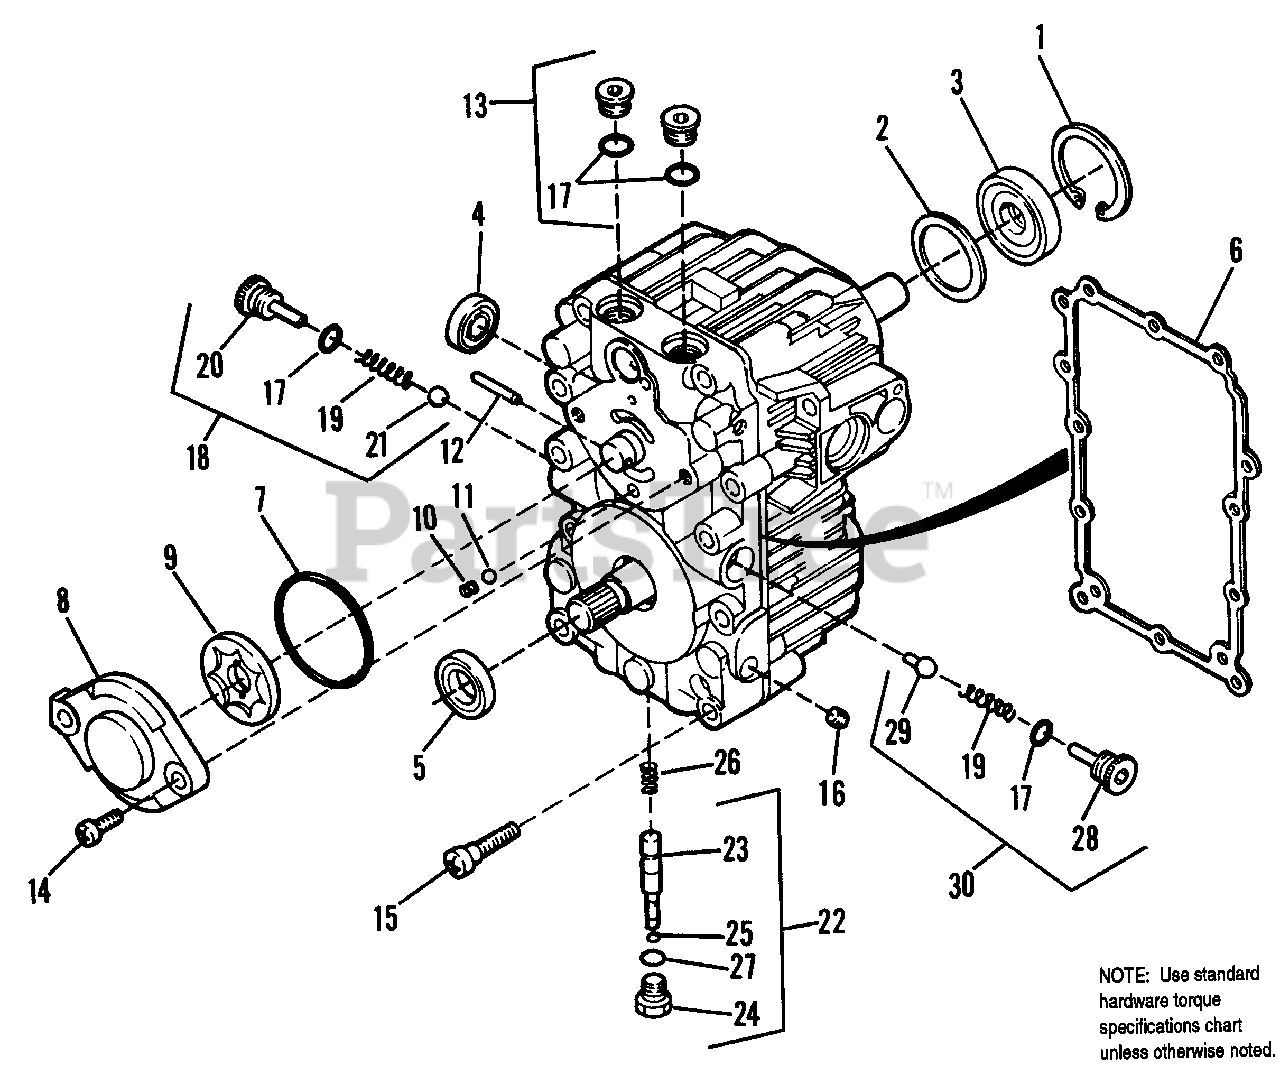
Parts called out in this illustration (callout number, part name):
1	RETAINING RING
2	SPACER
3	SEAL
4	SEAL
5	LIP SEAL
6	GASKET, Center Section
7	O-RING, Rubber
8	CHARGE PUMP HOUSING
9	GEROTOR ASSEMBLY
13	BOSS PLUG, O-Ring
14	SCREW, M8 x 20
15	SCREW, M8 x 35
17	O-RING, Rubber
18	CHECK VALVE KIT (Incl. Ref. Nos.17, 19, 20, 21)
19	SPRING
20	CHECK VALVE PLUG
22	BY-PASS VALVE KIT (Incl. Ref. Nos. 23-27)
23	BY-PASS SPOOL
24	BY-PASS PLUG
25	O-RING
27	O-RING, Rubber
28	PLUG
29	POPPET, Orifice
30	CHECK VALVE KlT, Poppet (Incl. Ref. Nos. 17, 19, 28, 29)
31	OVERHAUL SEAL KIT (Incl. Ref. Nos. 1-7, 17, 25, 27)
